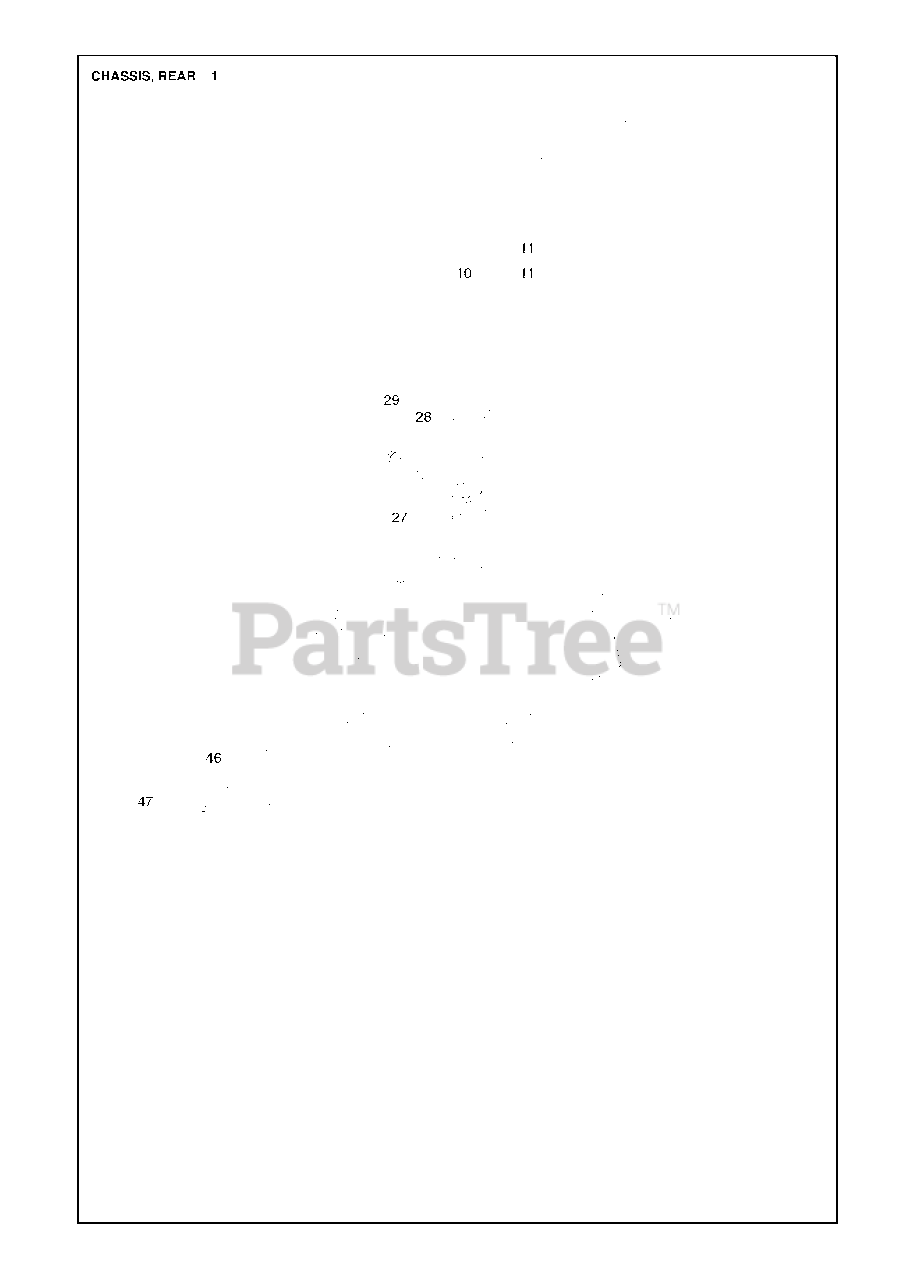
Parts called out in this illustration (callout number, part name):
11	BUSHING
46	DRAW RING
47	SCREW M10X25
